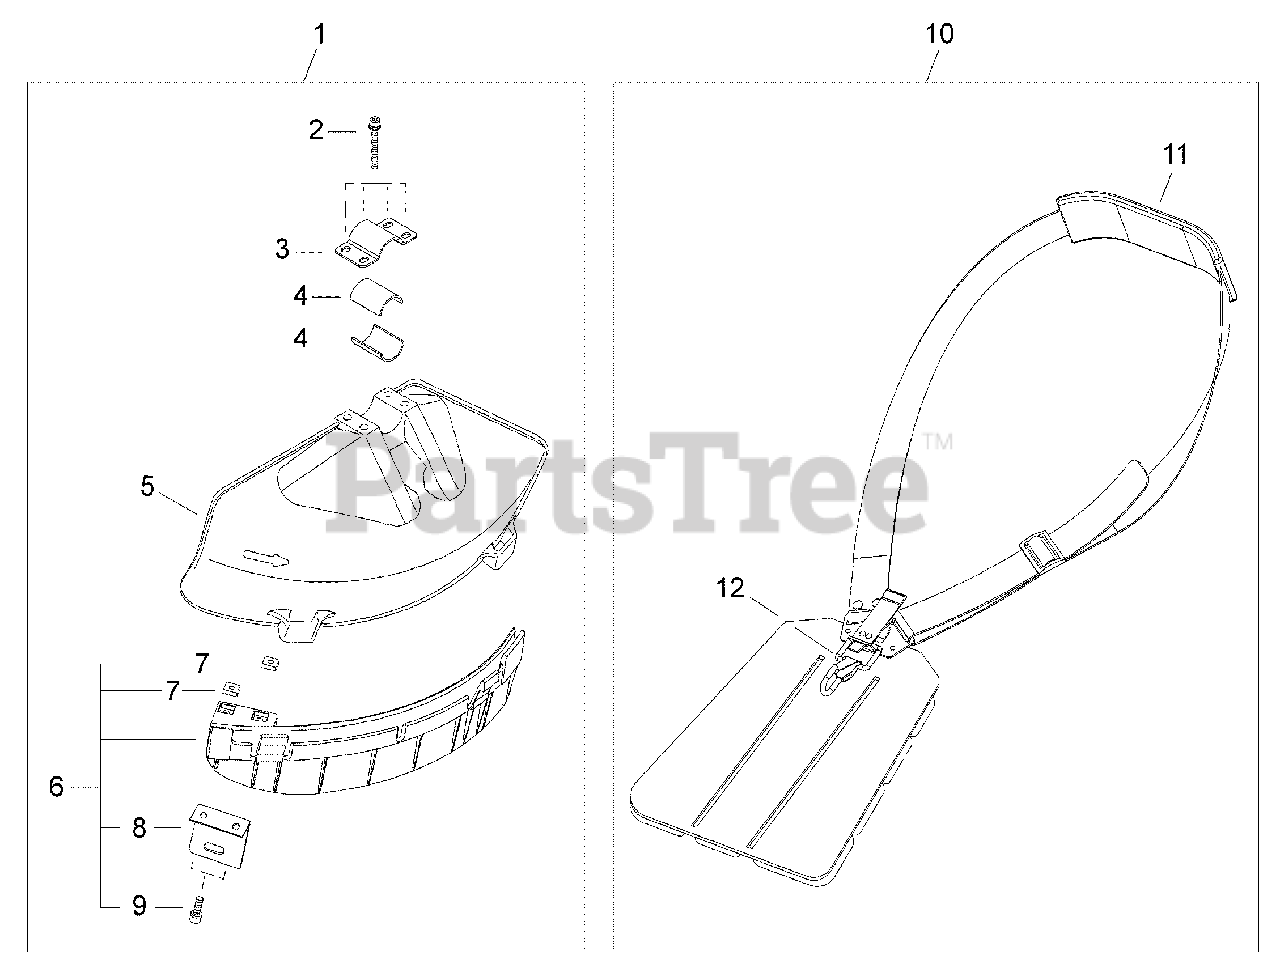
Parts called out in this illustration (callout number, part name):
1	DEBRIS SHIELD KIT
2	SCREW - 5X45
3	CLAMP - UPPER
4	SPACER
5	SHIELD, DEBRIS
6	SHIELD GUARD KIT
7	NUT - 5
8	KNIFE, TRIMMER LINE
9	SCREW - 5X16
10	HARNESS ASSY
11	PAD
12	HOOK
